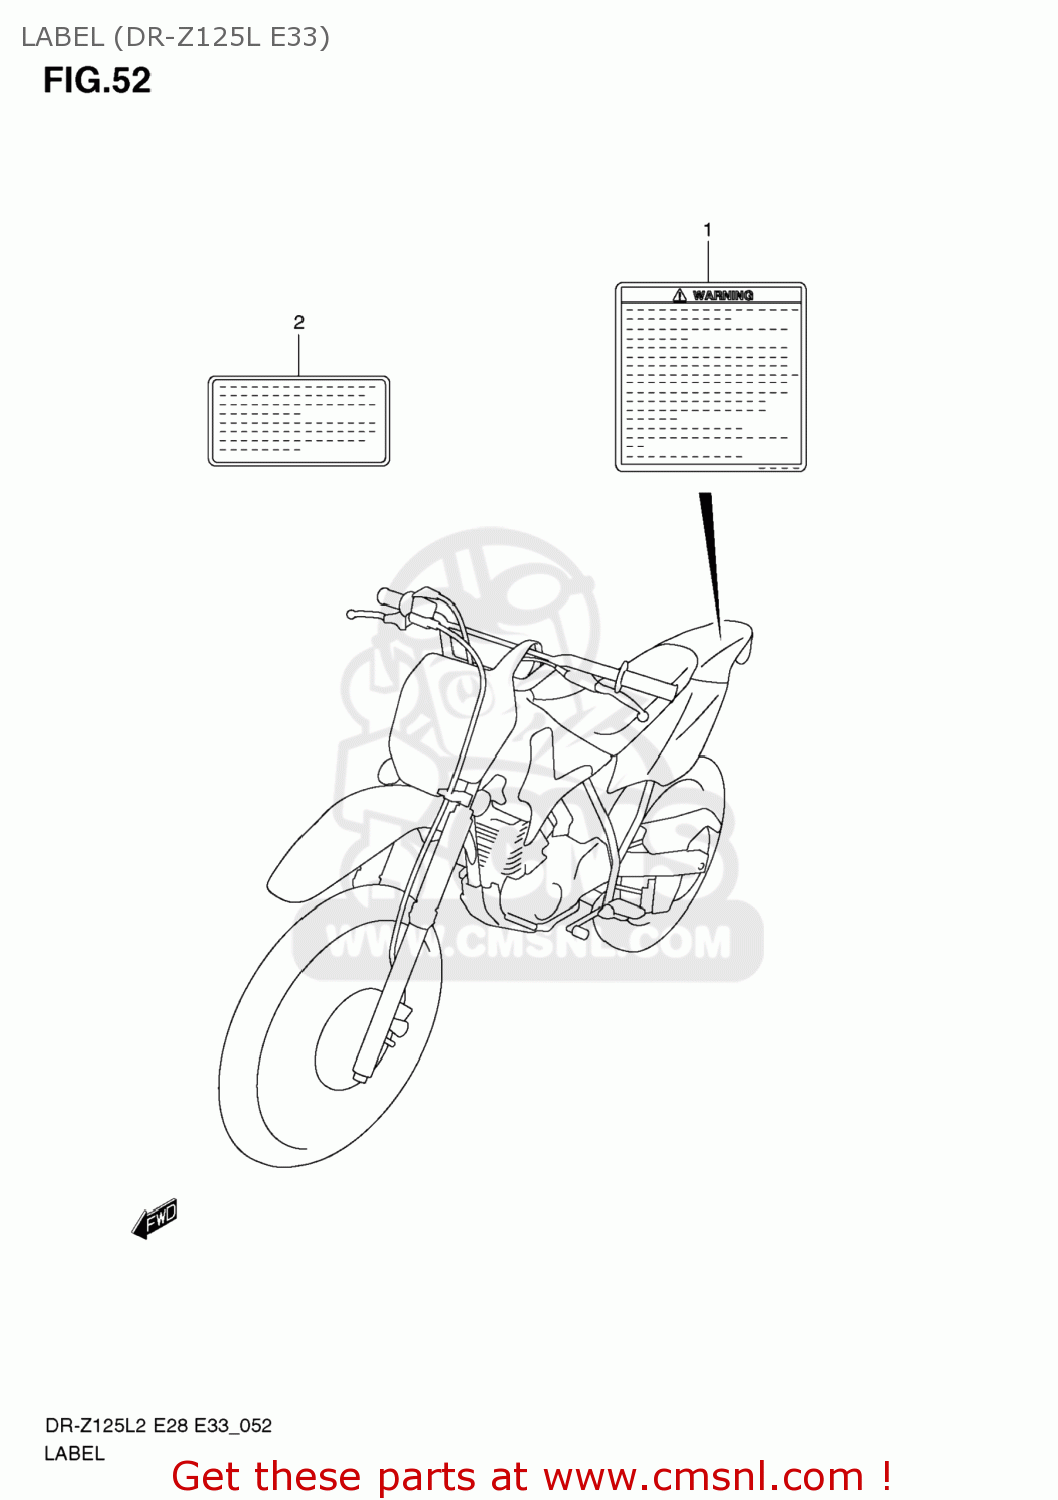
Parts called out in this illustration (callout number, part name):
1	LABEL,GENERAL WARNING
2	LABEL,MANUAL NOTICE
3	MANUAL,OWNER'S
